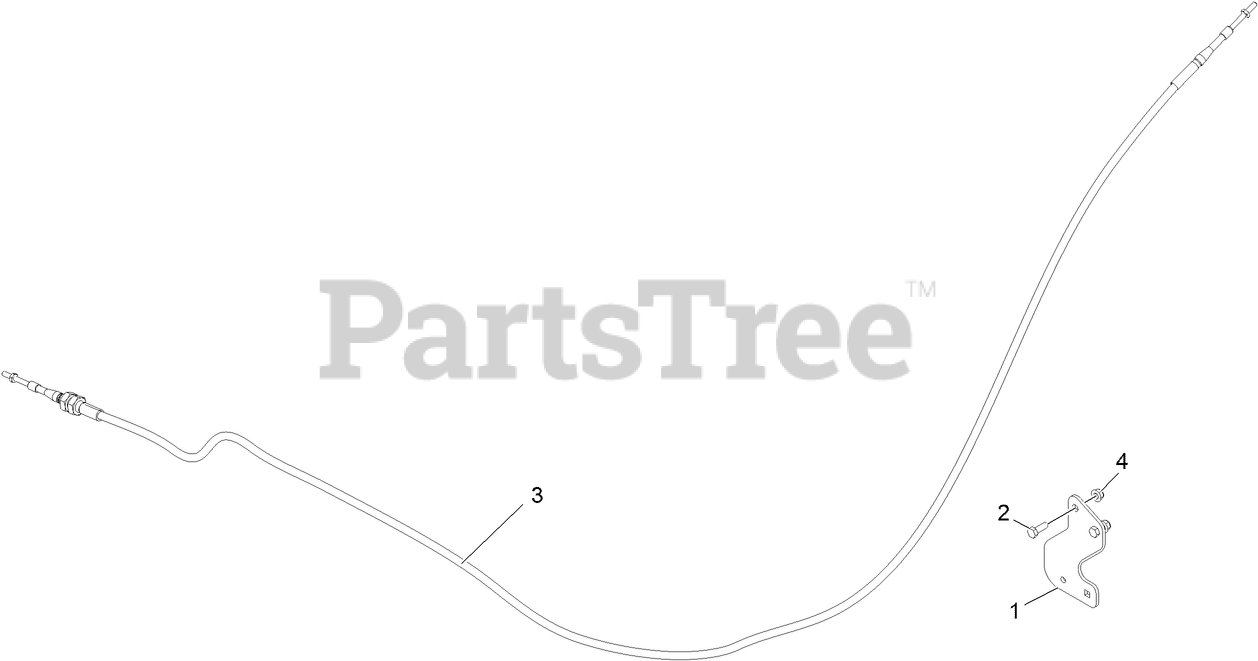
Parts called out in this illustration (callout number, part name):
2	SCREW-HH
3	CABLE-HAND DISCHARGE GATE, 100 INCH
4	NUT-HF, NI
